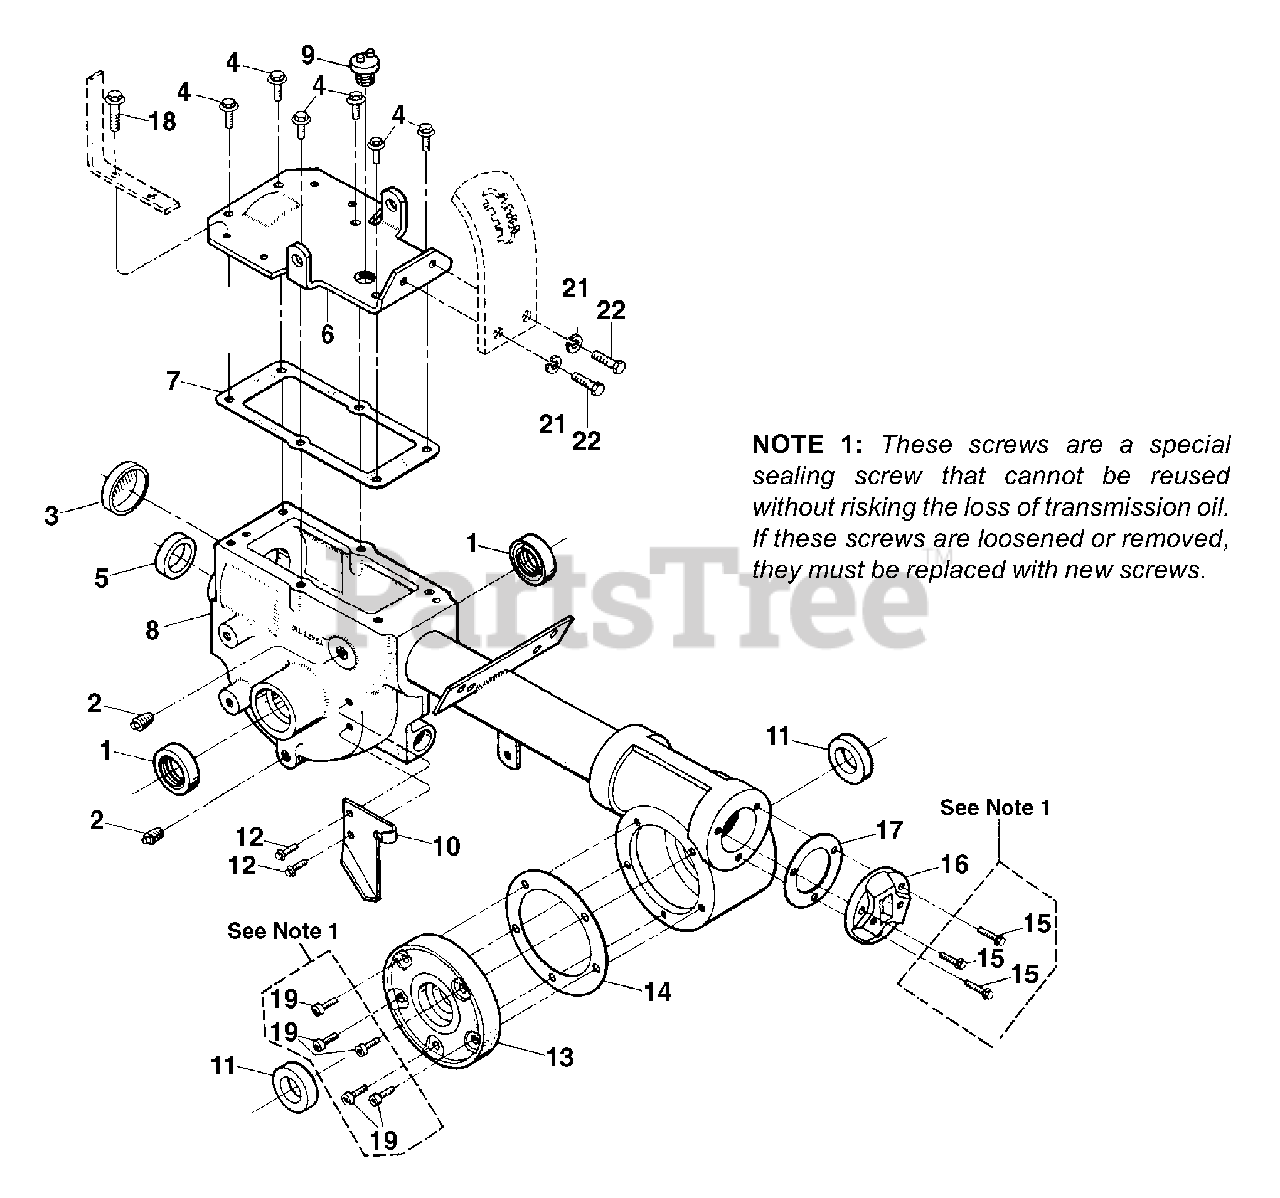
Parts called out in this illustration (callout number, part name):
1	Oil Seal (Double Lip), Wheel Shaft
2	Pipe Plug, 1/4,
3	Seal, Transmission Bore
4	Hex Flange Screw, 5/16-18 x 3/4
5	Oil Seal, Input Pinion Shaft
6	Transmission Cover (Incl. four Ref. 18 and two ea. Refs. 21 & 22)
7	Gasket, Transmission Top Cover
8	Transmission Case Assy. (Incl. Tube and Rear Housing)
10	Mounting Plate, Wheel Clutch Cable
11	Oil Seal, Tiller Shaft
12	Hex Flange Screw, 5/16-18 x 5/8
13	Tiller Housing Cover, left side
14	Gasket, Tiller Housing Cover, .010" (fits all covers)
15	Screw Kit: Incl. three 1/4-20 x 7/8 Self-Sealing Screws
16	Rear Bearing Cap
17	Gasket, Rear Bearing Cap, .010" Thick
18	Hex Flange Screw, 5/16-18 x 1
19	Screw Kit Incl. five 1/4-20 x 5/8 Self-Sealing Screws
21	Lockwasher, 3/8
22	Hex Hd. Screw, 3/8-16 x 3/4
